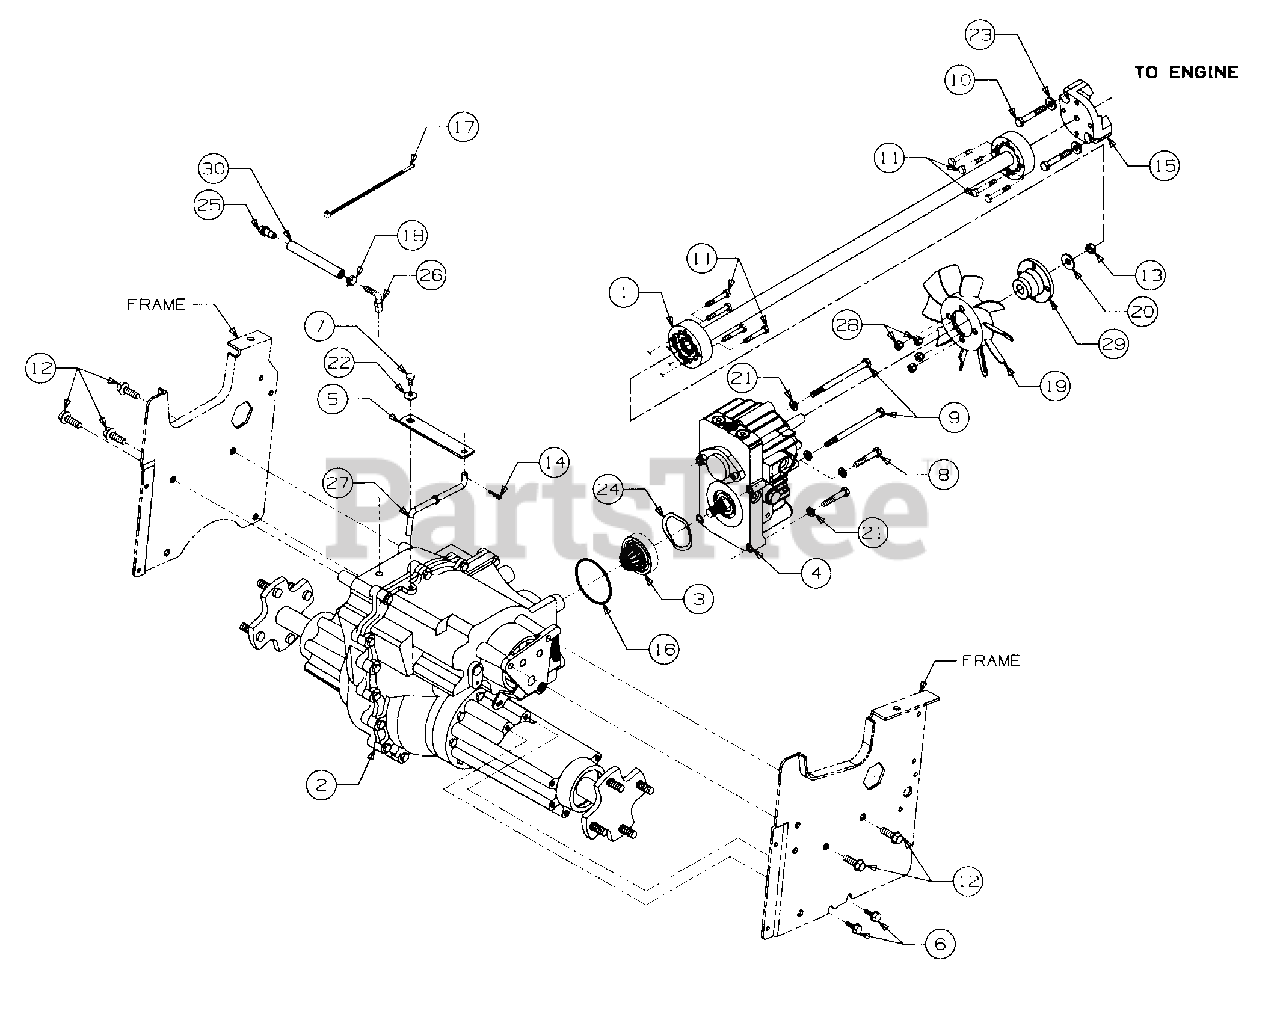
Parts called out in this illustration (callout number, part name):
1	Shaft Assy, Drive, 27.87 Lg
2	Transmission, Hydro
3	Pinion Assy, Input
4	Pump, Hydrostatic
5	Arm, Hydro Dump
6	Screw, Hex Wash Sf-Tapp 5/16-18 X.75 Lg
7	Screw, Hex Cap Wash TT-Tapp, 1/4-20 x .75 Lg GR5
8	Screw, Hex Cap, 5/16-18 x 1.75 Lg GR5
9	Screw, Hex Cap, 5/16-18 x 4.5 Lg GR5
10	Bolt, Hex Patch, M8-1.25 x 50 mm
11	Bolt, Hex Patch, 1/4-20 x 1.62 Lg GR5
12	Screw, Hex Wash Tapp 3/8-16 x 1.25 Lg
13	Nut, Hex Center Lock Jam 3/8-24
14	Pin, Internal Cotter, 5/16 Dia
15	Adapter, Drive Shaft
16	O-Ring, 2.75 x .103
17	Tie, Self-Clinch Cable
18	Clamp, Hose
19	Fan, 10 Blade Cooling x 1.12 Lg
20	Washer, Bell, .380 x .88 x .062 Thk
21	Washer, Lock, 5/16
22	Washer, Bell, .265 x .75 x .062 Thk
23	Washer, Flat, .312 x .750 x .119 Thk
24	Washer, Spring Wave, 1.96 x 2.44 x .06 Thk
26	Fitting, Elbow
27	Rod, Hydro Disengagement
28	Nut, Fan, 1/4-20
29	Adapter, Pump
30	Line, Fuel, 7 in. Lg
